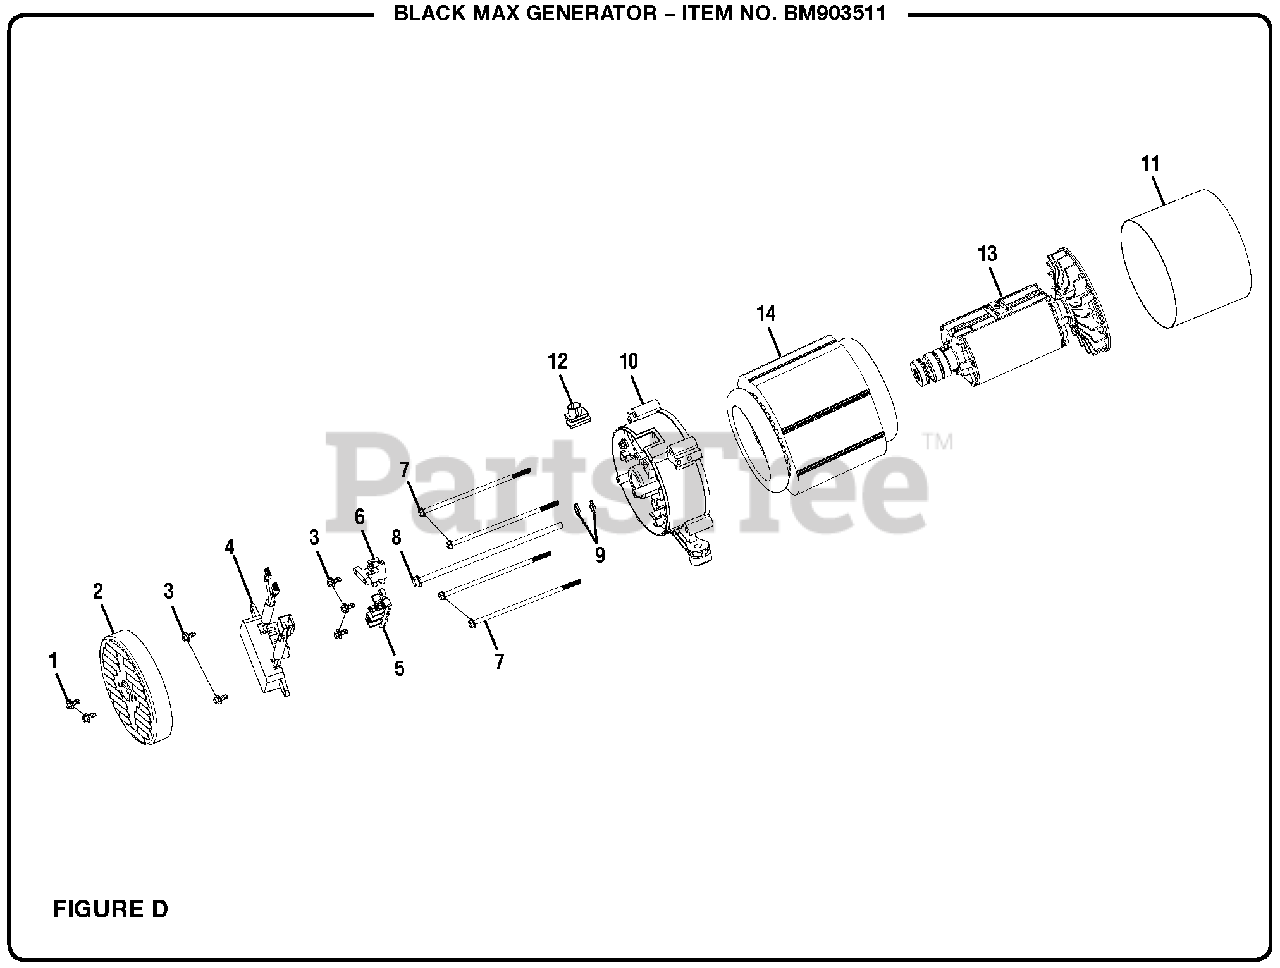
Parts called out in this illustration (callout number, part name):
1	Bolt (M5 x 12 mm, Hex Hd.)
2	Brush Cover
3	Bolt (M5 x 16 mm, Hex Hd.)
4	Automatic Voltage Regulator
5	Terminal Block
6	Brush Assembly
7	Stator Bolt
8	Rotor Bolt
9	Rotor Washer
10	Bearing Support
12	Rubber Boot
13	Rotor Assembly
14	Stator Assembly
